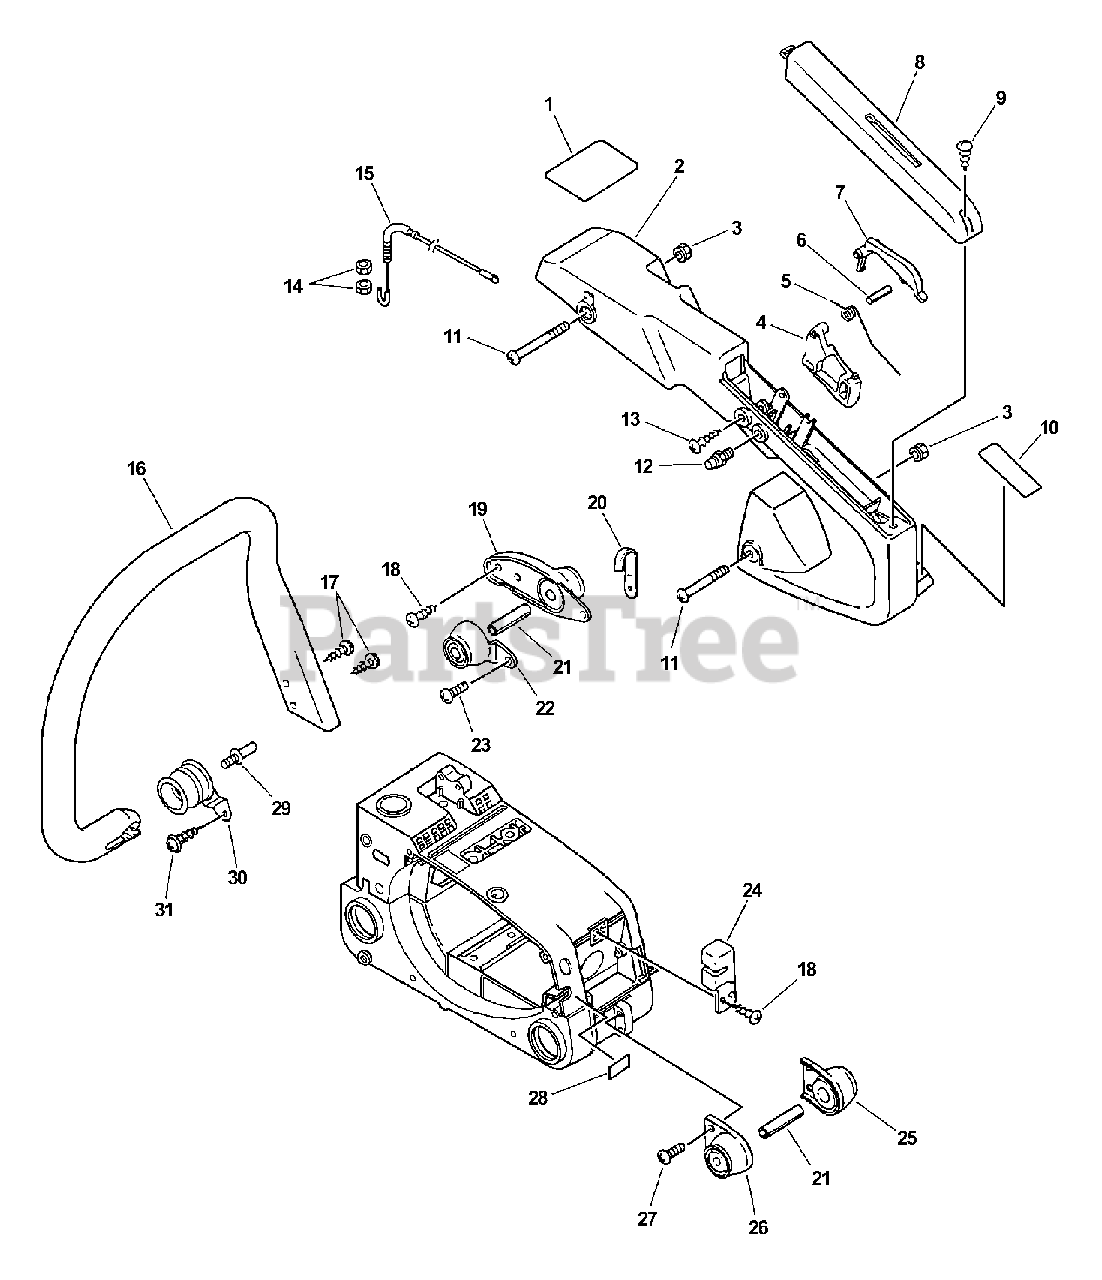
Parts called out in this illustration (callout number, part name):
1	LABEL - KICK BACK
2	HANDLE - REAR
3	NUT - 5 -- FLANGE
4	TRIGGER, THROTTLE
6	ROLLER - 4X19.8
7	LOCKOUT, THROTTLE
8	COVER, HANDLE
9	SCREW - 4X22
10	LABEL - CAUTION
11	SCREW - 5X57
12	LATCH, THROTTLE
13	SCREW - 4X25
15	CABLE, THROTTLE
16	HANDLE - FRONT
17	SCREW - 5X20 -- TAPPING
18	SCREW - 4X14
19	CUSHION - UPPER
21	COLLAR - 6
22	CUSHION - UPPER
23	SCREW - 4X10
25	CUSHION - LOWER
26	CUSHION - LOWER
27	SCREW - 4X14
28	LABEL - STOP
31	SCREW - 4X16
